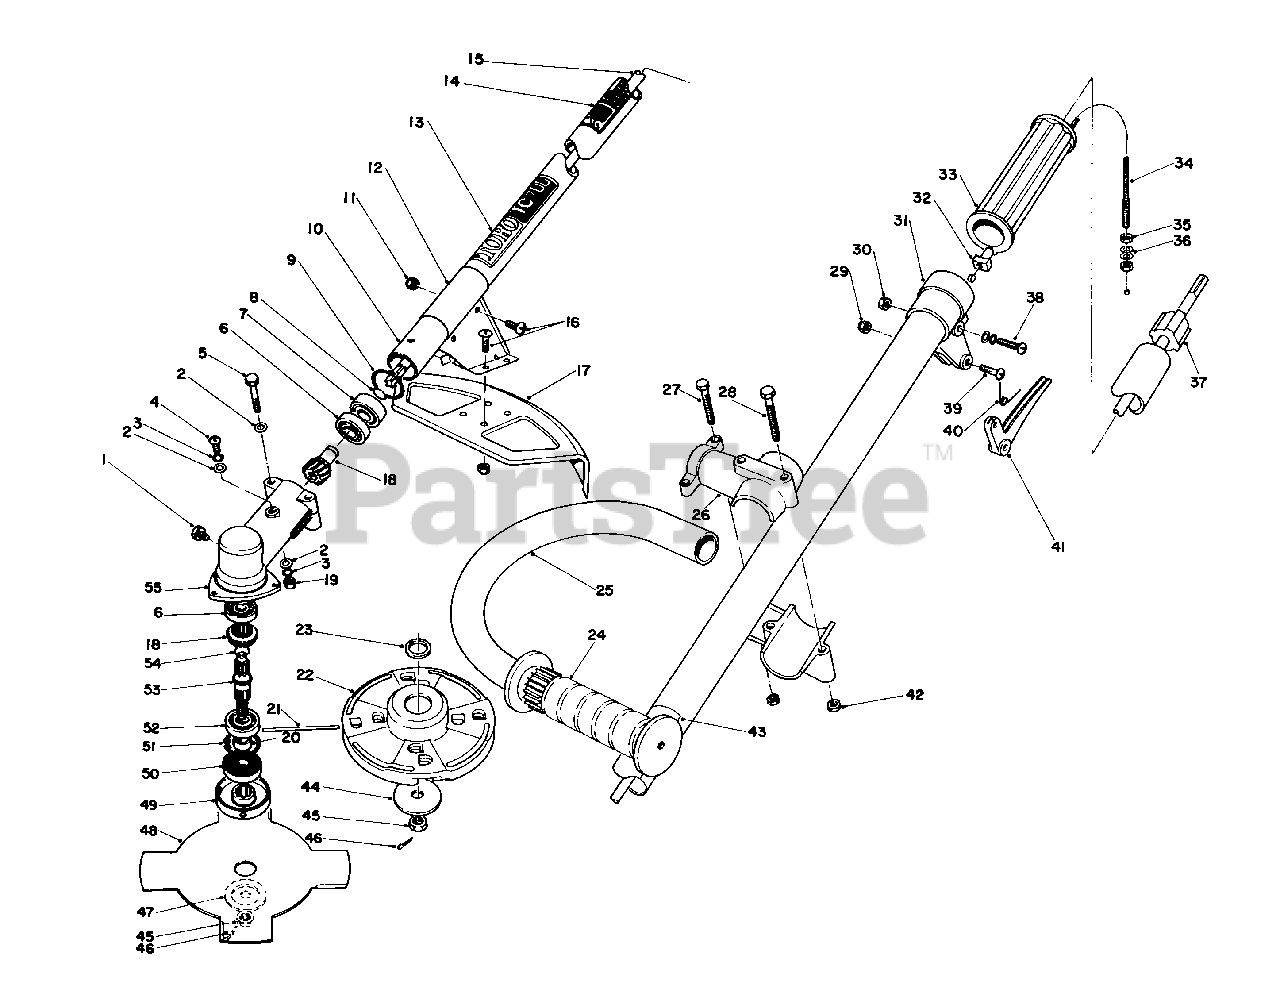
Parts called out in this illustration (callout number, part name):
3	Spring Washer
6	Ball Bearing
7	Ball Bearing
10	Housing Assembly
12	Bracket-Shield
13	Decal-TC 700
15	Shaft-Drive
16	Screw-Machine Rd. Hd.
18	Gear Set
19	Nut
21	Filament Line Pkg. (24 Pcs.)
22	Cutter Head (Incl. #23)
23	Spacer-Cutter Head
24	Hand Grip
25	Tube-"J" Handle
26	Clamp-"J" Handle
27	Screw-Machine Rd. Hd.
28	Screw-Machine Rd. Hd.
30	Nut
31	Bracket, Trigger
34	Throttle Cable
36	Washer
37	Bushing
40	Spring-Return
41	Throttle-Trigger
43	Decal-Warning
44	Plate-Washer
46	Cotter Pin
47	Blade Adapter Kit (Incl. Ref. #45 & 46)
48	Brush Blade
49	Plate-Blade Fixing
50	Oil Seal
52	Ball Bearing
53	Shaft-P.T.O.
55	Gear Housing
